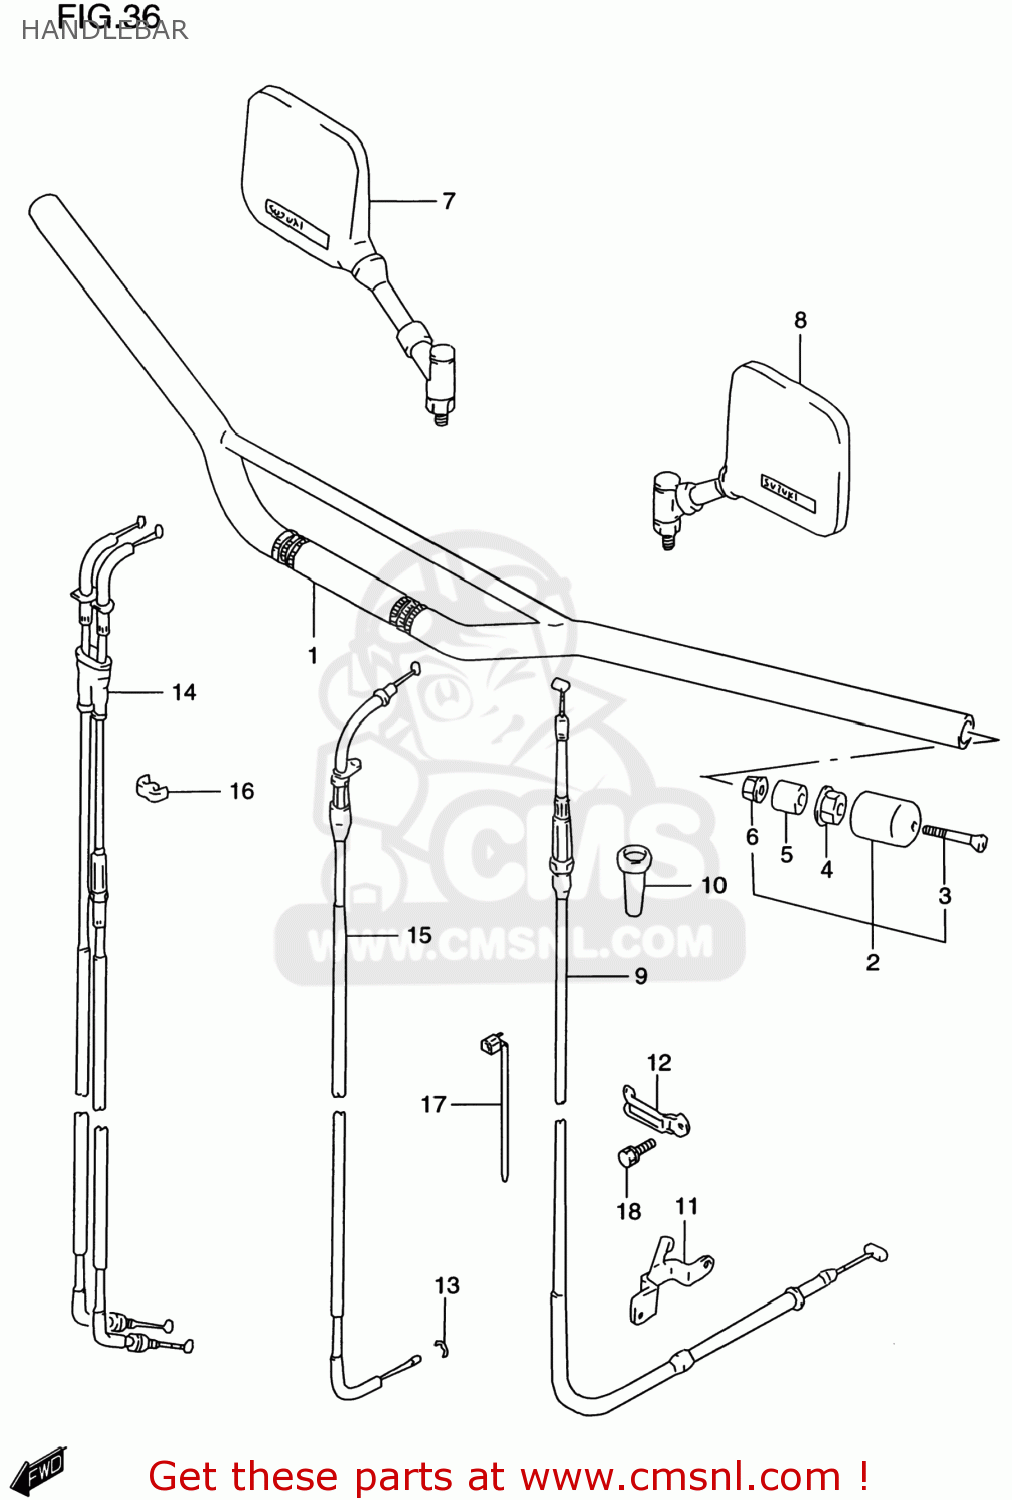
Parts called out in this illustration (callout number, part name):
1	HANDLEBAR(BLACK)
2	BALANCER SET,HANDLEBAR
3	SCREW
4	NUT
5	EXPANDER,HANDLE BALANCER
6	NUT
7	MIRROR ASSEMBLY,REAR VIEW
8	MIRROR ASSEMBLY,REAR VIEW
9	CABLE ASSY,CLUTCH
10	BOOT,CLUTCH CABLE
11	STOPPER,CLUTCH CABLE
12	CLAMP
13	E RING
14	CABLE ASSY,THROTTLE
15	CABLE,STARTER
16	CLIP
17	CLAMP(L:235)
18	BOLT
19	CAP
